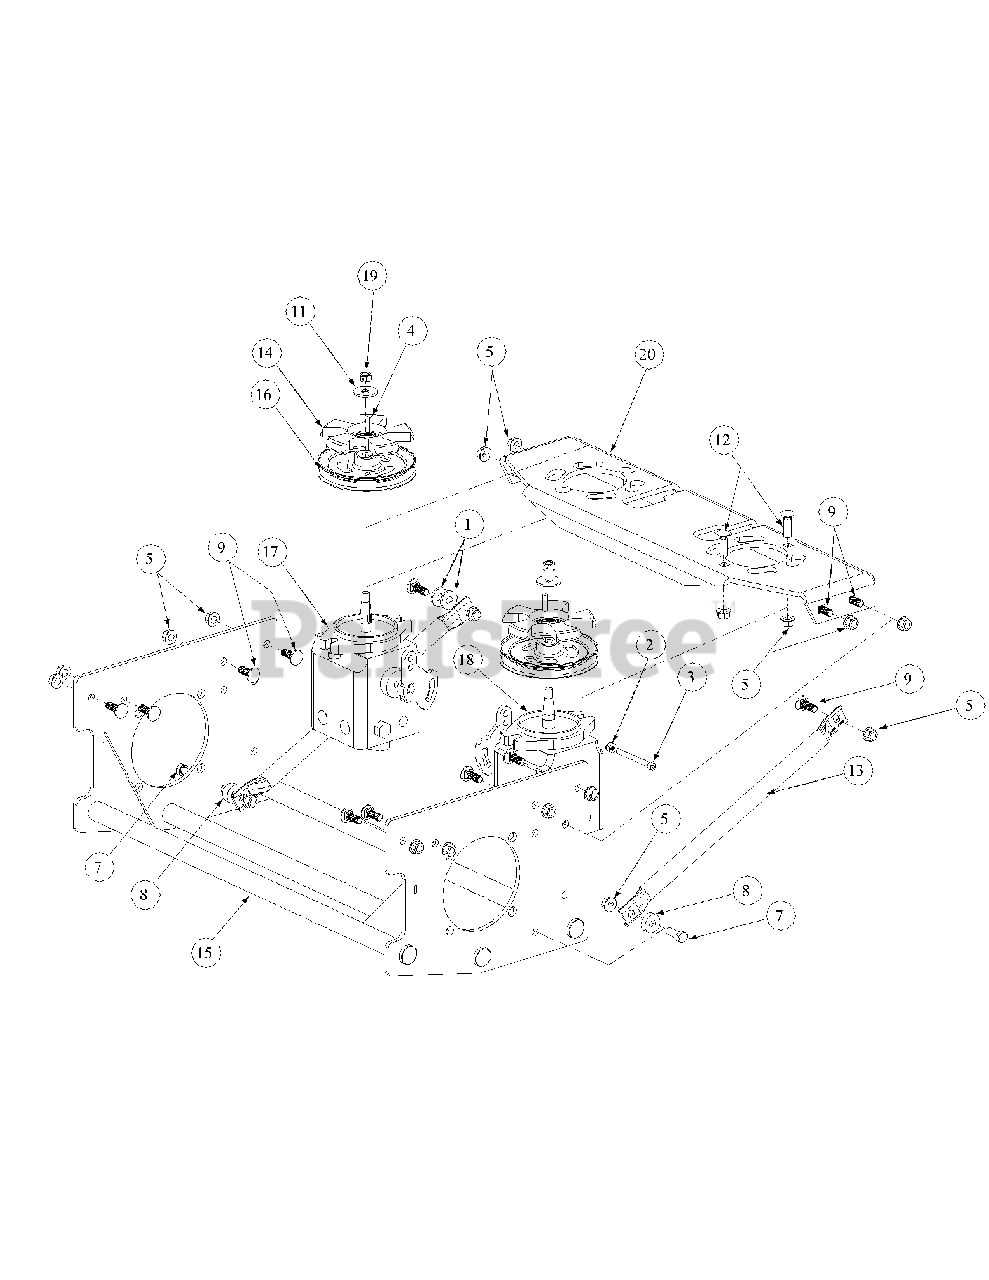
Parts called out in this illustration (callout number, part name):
1	Washer lock 3/8 zinc
2	Lock Nut, Nylon Insert, 1/4-20
3	Socket Head Cap Screw, 1/4-20 x 2-1/2
4	Key, 3/16" x 7/8"
5	Flange Lock Hex Nut, 3/8-16
7	Hex Cap Screw, 2/8 -16 x 1.25
8	Spacer, .406 ID x 1.00 OD x .38
9	Carriage Bolt, 3/8-16 x 1
11	Flat Washer, .411 x 1.25 x .100
12	Carriage Screw, 3/8-16 x 1.25
14	Hydro Pulley Fan
15	Hydro Motor Frame Assembly
16	Hydro Pulley Pump
17	Hydro Pump, LH
18	Hydro Pump, RH
19	Hex Nut, 3/8-24
20	Hydro Pump Mounting Weldment
